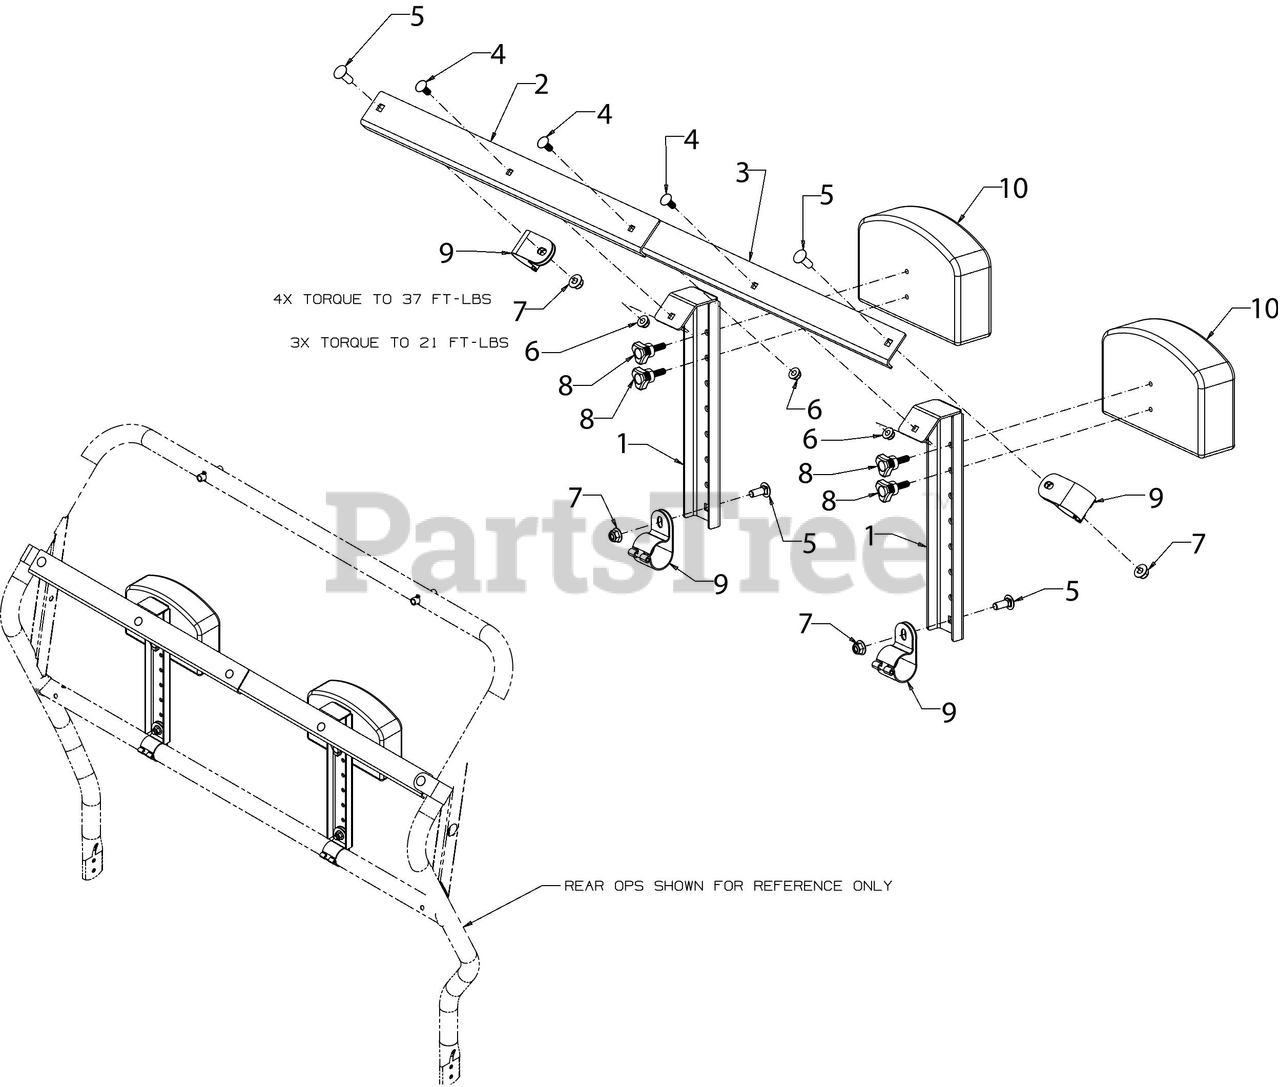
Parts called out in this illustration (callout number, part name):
4	CARRIAGE BOLT 5/16-18 x .75
5	CARRIAGE BOLT 3/8-16 x 1.00 GR5
6	FLANGE LOCK NUT 5/16-18
8	KNOB ASSEMBLY 5/16-18
10	HEADREST PAD
